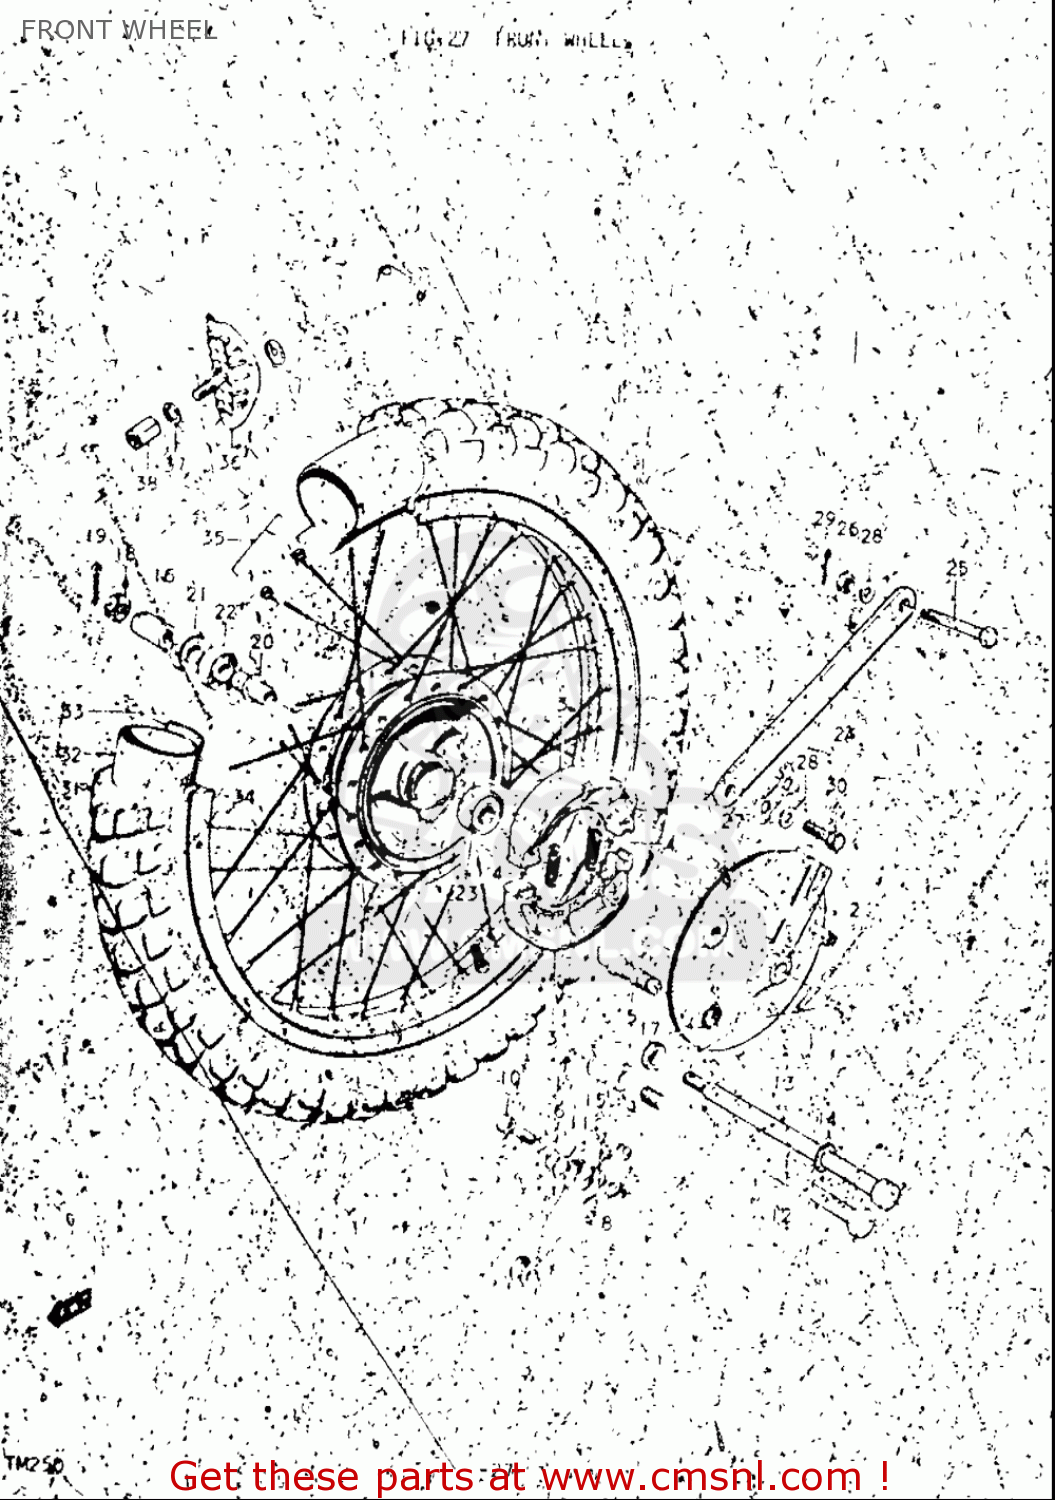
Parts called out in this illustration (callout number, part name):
4	SPRING(L:35.8)
5	CAM,FR BRAKE
6	O RING(D:2.5,ID:11.4)
8	WASHER
9	NUT
10	BOLT(6X31)
11	WASHER(12.5X20X1)
12	AXLE,FR
13	AXLE,FR
14	WASHER
15	NUT,FRONT AXLE
18	NUT (12MM)
19	COTTER PIN
21	OIL SEAL(17X38X5)
22	BEARING
23	BEARING
24	LINK, FRONT TORQUE
26	NUT
27	MUD FLAP,FRONT FENDER,LEFT
28	WASHER
30	BOLT
32	TUBE ASSEMBLY,WHEEL,INNER
33	PROTECTOR,WHEEL INNER
36	STOPPER,BEAD(1.85)
37	WASHER
